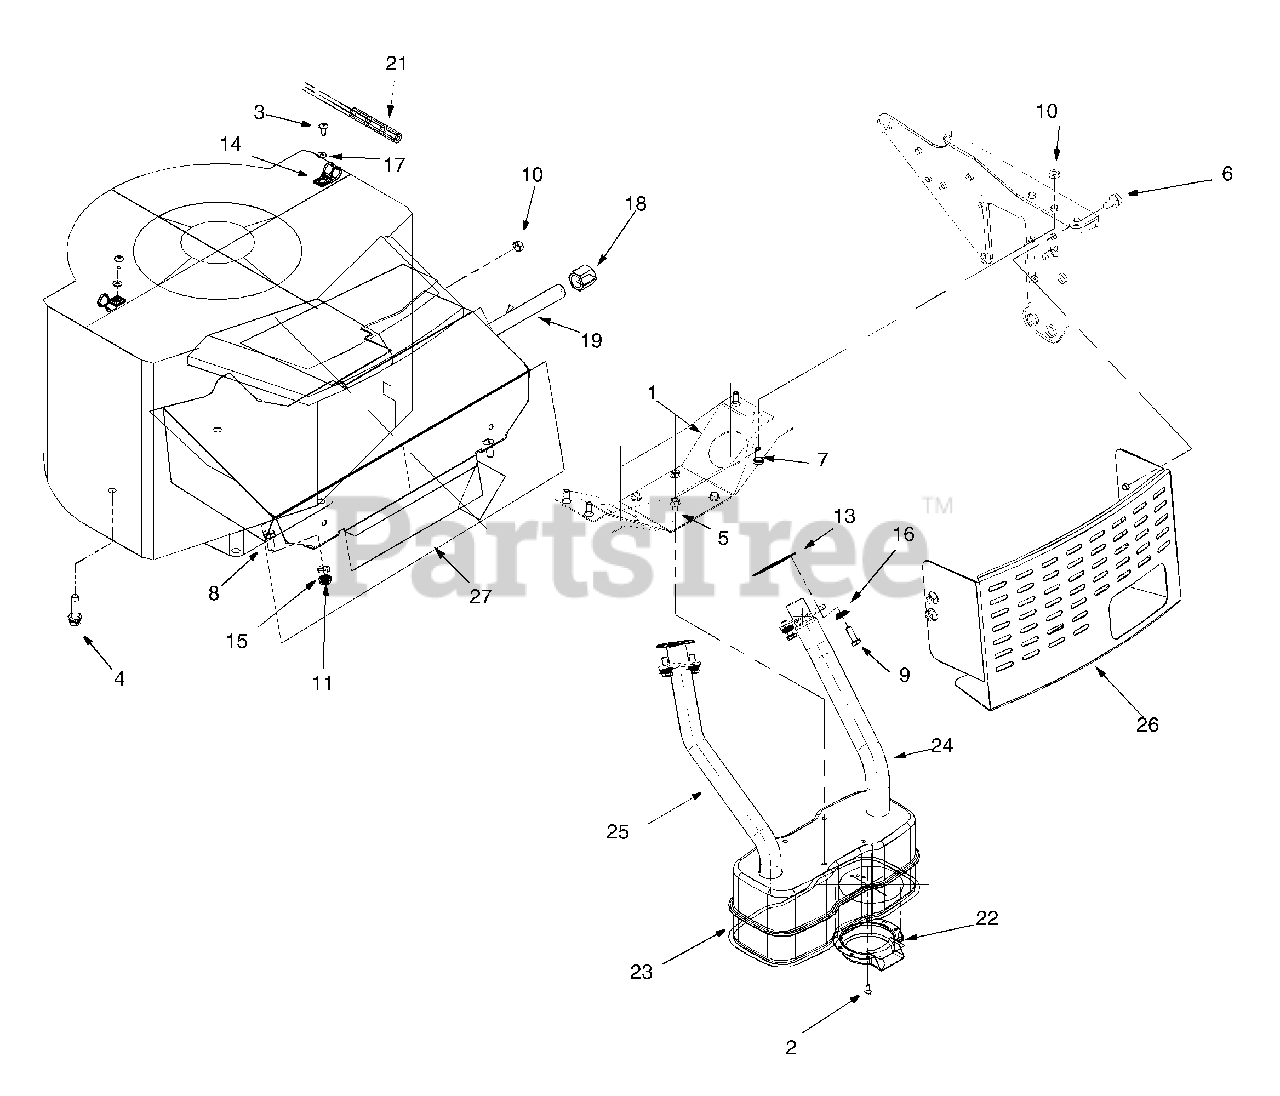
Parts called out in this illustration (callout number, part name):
1	Muffler Mounting Brkt.
2	Hex Wash Hd. Scr. #8-32 x .375" Lg.
3	Pan Hd. Scr. #10-16 x .5" Lg.
4	Hex Wash. Hd. Scr. 3/8-16 x 1.25"
5	Hex Wash. Hd. Scr. 1/4-20 x .5" Lg.
6	Hex Wash. Hd. Scr. 5/16-18 x .625"
7	Hex Bolt 1/4-20 x .62" Lg.
8	Hex Bolt 5/16-18 x .75" Lg.
9	Hex Bolt 1/4-20 x .75" Lg.
10	Hex Sems Nut 1/4-20 Thd.
11	Hex Nut 5/16-18 Thd.
13	Exhaust Gasket
14	Clamp
15	L-Wash. 5/16" I.D.
16	L-Wash. 1/4" I.D.
17	Fl-Wash. .188" I.D. x .437"
18	Oil Drain Cap
19	Straight Pipe 3/8-18 NPT. x 5" Lg.
21	Fuel Line 46" Lg.
22	Muffler Deflector
23	Muffler
24	Exhaust Pipe-L.H.
25	Exhaust Pipe-R.H.
